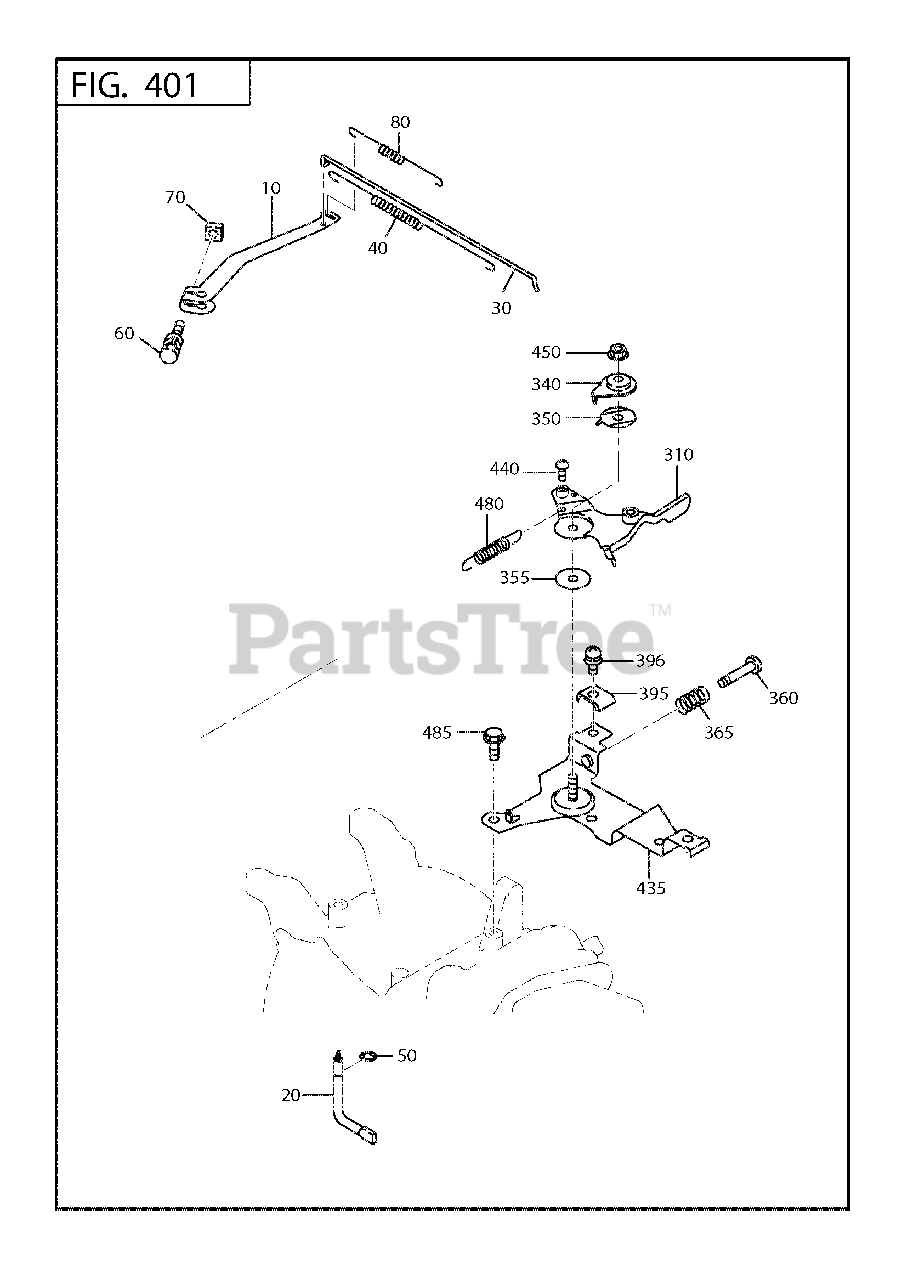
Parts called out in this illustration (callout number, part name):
10	GOVERNOR LEVER
20	GOVERNOR SHAFT
30	GOVERNOR ROD CP
60	BOLT AND WASHER
80	GOVERNOR SPRING
310	SPEED CONTROL LEVER
355	FRICTION WASHER
360	SCREW, PANHEAD
365	SPRING, ADJUST
435	SPEED CONTROL BRACKET
